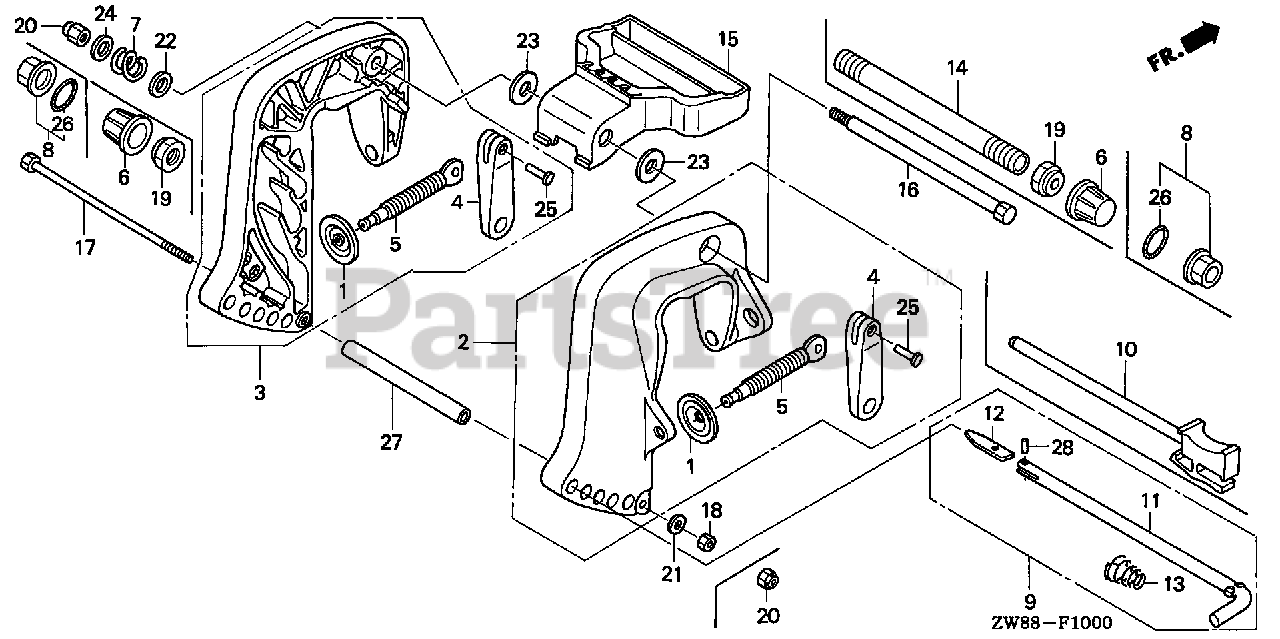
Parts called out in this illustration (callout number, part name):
1	PLATE, PUSH
2	BRACKET, R. STERN *NH282MU* (OYSTER SILVER METALLIC-U)
3	BRACKET, L. STERN *NH282MU* (OYSTER SILVER METALLIC-U)
4	GRIP, CLAMP
5	SCREW, CLAMP
7	SPRING, TILT
7	SPRING, TILT (NOT AVAILABLE)
10	ROD, ADJUSTING
15	HANDLE, CARRYING
16	BOLT, TILTING
17	BOLT, HEX. (6X160)
18	NUT, HEX. (6MM)
20	NUT, SELF-LOCK (8MM)
21	WASHER, PLAIN (6MM)
22	WASHER, PLAIN (10MM)
23	WASHER (10MM)
24	WASHER (8MM)
25	RIVET (4X22.6)
27	COLLAR, DISTANCE (6MM)
